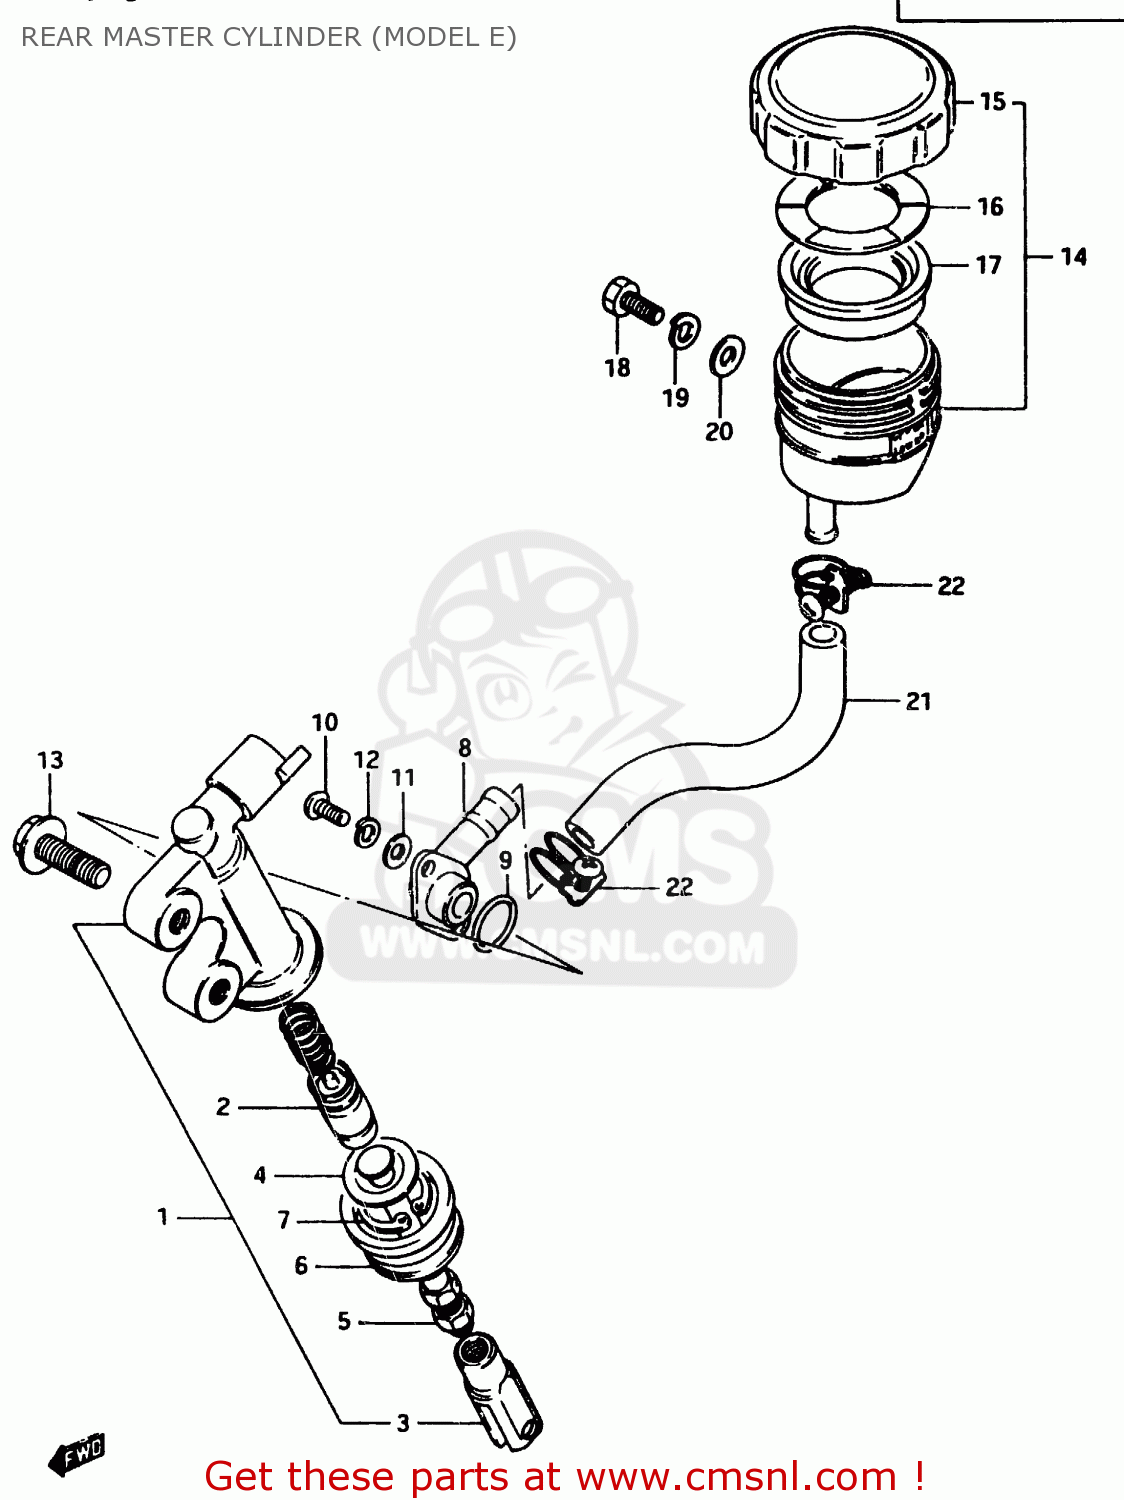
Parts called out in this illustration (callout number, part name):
1	CYLINDER ASSY,RR MASTER
2	PISTON/CUP SET
3	YOKE
4	ROD,PUSH
5	NUT,MASTER CYLINDER
6	BOOT
7	CIRCLIP
8	CONNECTOR,HOSE
9	O RING
10	SCREW
11	WASHER
12	LOCK WASHER
13	BOLT
14	TANK ASSEMBLY,RESERVOIR
15	CAP
16	PLATE,DIAPHRAGM
17	DIAPHRAGM
18	SCREW(6X12)
19	LOCK WASHER
20	WASHER
21	HOSE,RESERVOIR TANK
22	CLAMP
